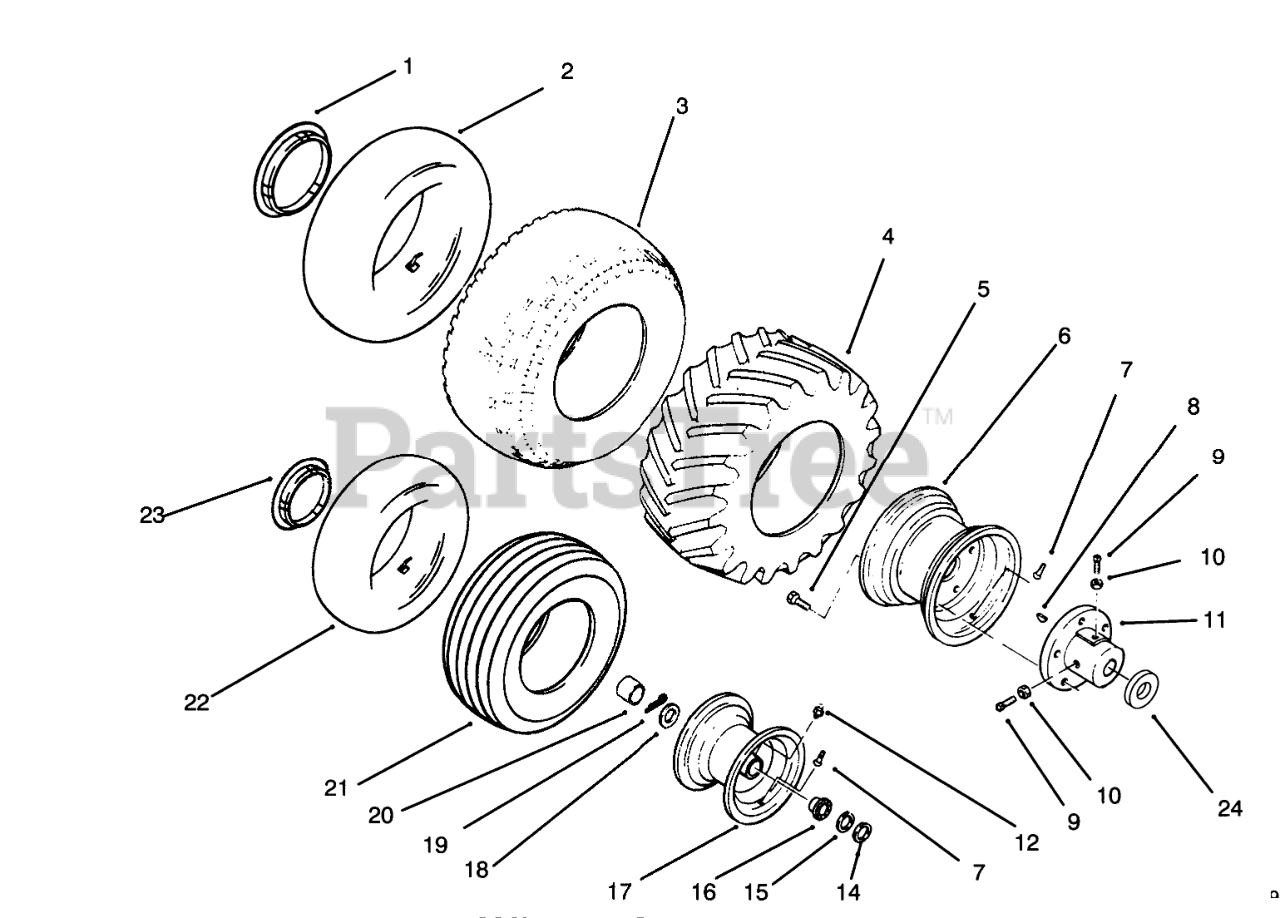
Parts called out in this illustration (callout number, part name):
1	12"-HUB CAP LOGO
2	TUBE-INNER
3	TIRE
4	Tire-Cleat, Rear
5	BOLT-LUG
6	WHEEL
7	VALVE
8	KEY-WOODRUFF
9	SCREW-SET, SQH
10	NUT-JAM
11	Hub Rear
12	ZERK-GREASE
14	WASHER-SHIM
15	WASHER
16	BEARING-WHEEL
17	Wheel Assembly-Front (Incl. Ref. #7, 12, & 16)
18	WASHER WHEEL
19	PIN-COTTER
20	HUBCAP
21	Tire (16 x 6.5-8) 2-Ply -2 Wheel Axel
23	8"-HUB CAP LOGO
24	WASHER-THRUST
